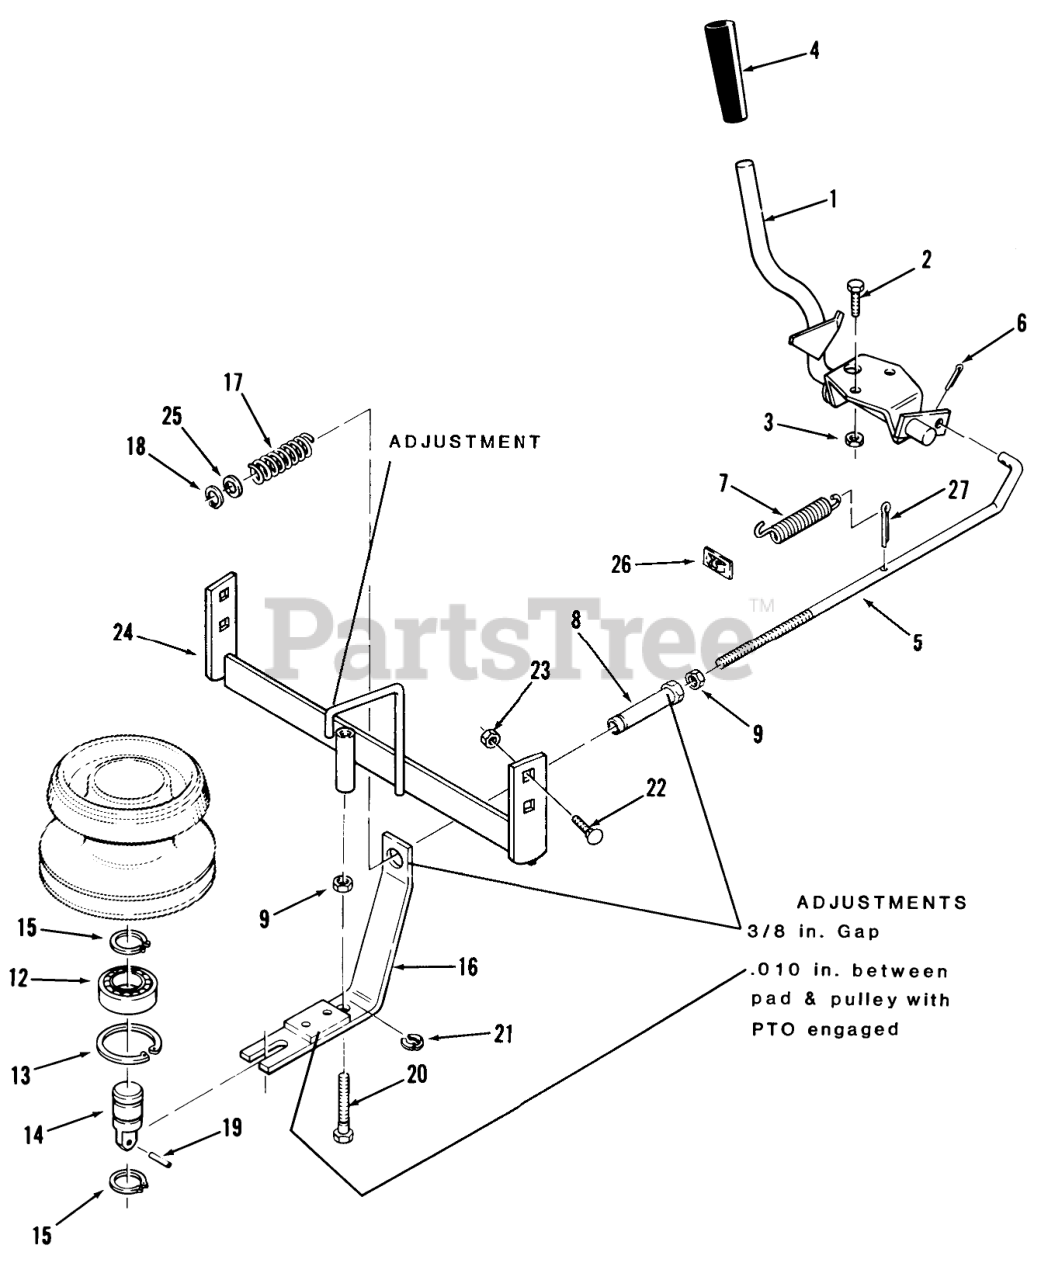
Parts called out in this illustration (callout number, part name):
1	ASSY HANDLE
2	Bolt
3	Nut
4	GRIP
5	PTO Clutch Rod
6	Cotter Pin
7	Spring
8	TUBE-CLUTCH SPACER
9	Jam Nut 5/16-18
12	BEARING-BALL
13	Ring-Snap
14	SHAFT CLUTCH HSG
15	RING-SNAP, EXTERNAL
16	ASM-CLUTCH BRAKE PTO
17	SPRING-CLUTCH
18	Retaining Ring
19	SPIROL PIN 7/32X7/8
20	SCREW-CLUTCH ADJUST
21	E-Ring
22	Bolt
23	Nut
24	Clutch Mounting Bracket
25	Washer
26	SPEED NUT
27	Pop Rivet
